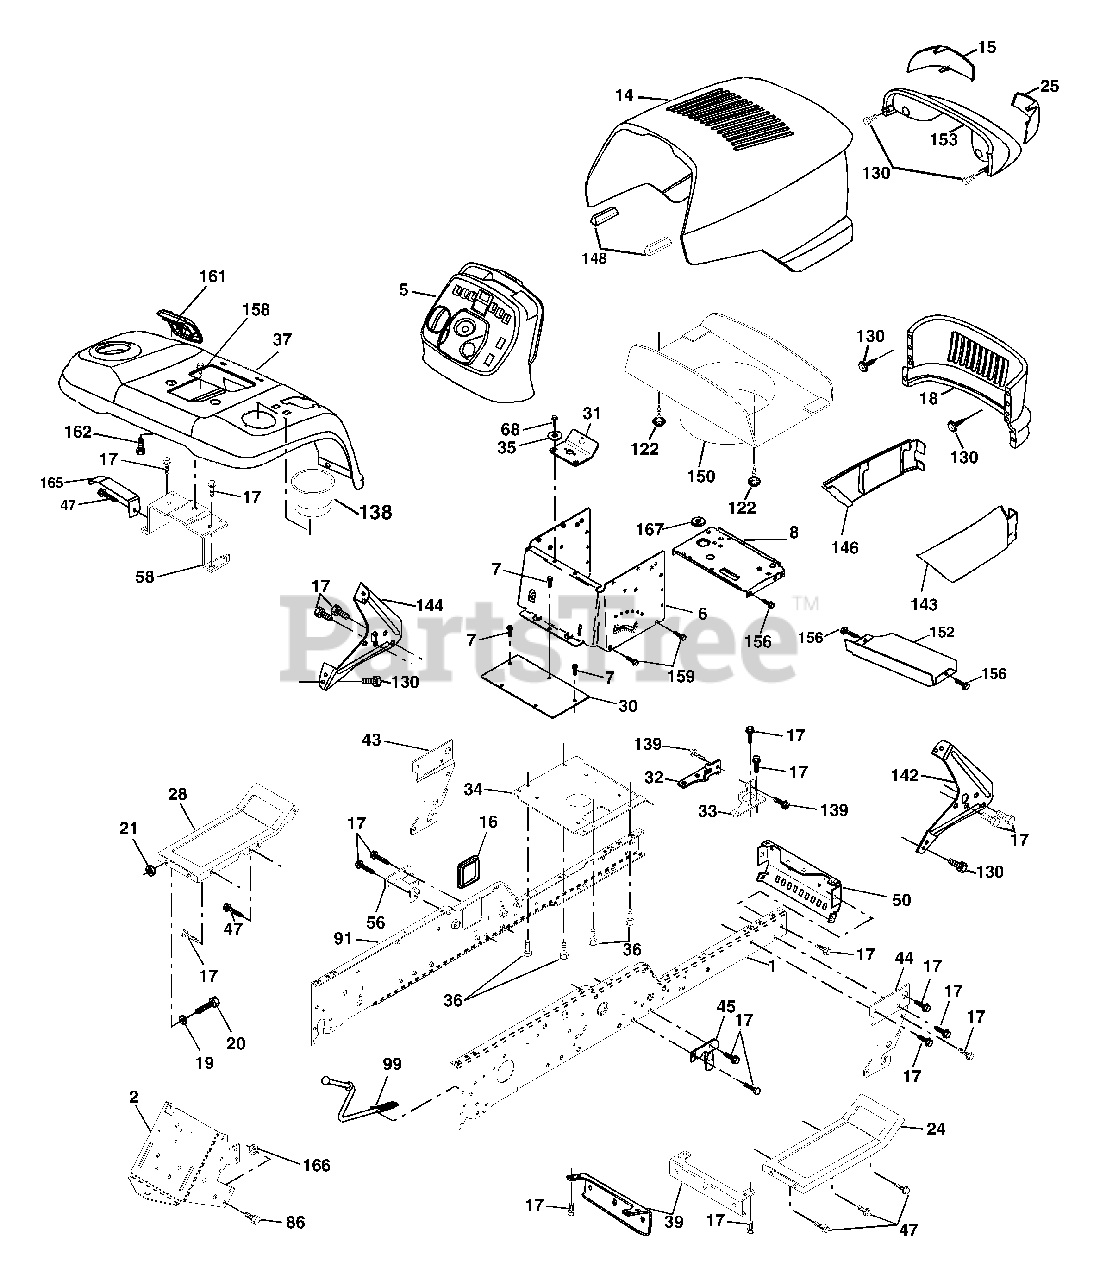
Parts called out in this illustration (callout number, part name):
1	Rail, Frame RH
2	Drawbar, Gt
5	Dash
6	Dash, 1PCS, Lower
7	Screw, Thd Cut 1/4-20 x 1/2
8	Support, Battery
14	Hood Asm., Pnt
15	Lens LH
16	Cover, Access
17	Screw, 3/8-16 x 3/4
19	Washer 13/32 x 13/16 x 12 Ga.
20	Bolt, Fin Hex 3/8-16 x 1
21	Nut, Crownlock 3/8-16
24	Footrest, RH
25	Lens RH
28	Footrest, LH
31	Bracket Supt 1-pc Vgt Steering
32	Bracket, Frame Pivot Lh
33	Bracket, Frame Pivot Rh
34	Plate Asm Engine Chassis
35	Washer 11/32 x 11/16 x 16 Ga.
36	Screw 5/16-18 x 3/4
37	Fender, Pnt.
39	Bracket, Axle Front
43	Bracket, Spnsn Front Lh
44	Bracket, Spnsn Front Rh
45	Bracket Asm., Susp Chassis Rh
47	Screw Thdrol 3/8-16 x 1/2
50	Bracket, Chassis Front
56	Bracket Asm., Susp Chassis Lh
58	Bracket Asm., Fender
68	Screw, 5/16-18 x 1/2
86	Bolt, Fin Hex 7/16-14 unc x 1-1/4
91	Rail, Frame Lh
99	Rod Asm. Bypass
122	Screw Hex WSHD 8-18 x 7/8
130	Screw Hw Hd Hi-Lo #13-16 x 3/4
138	Cupholder
139	Bolt Shoulder 5/16-18
142	Bracket Dash Stealth RH
143	Skirt Grille RH
144	Bracket Dash Stealth LH
146	Skirt Grille LH
148	Extrusion Bumper
150	Duct Heat Hood
152	Shield, Browning
153	Light Box Asm. w/Lens
156	Screw 5/16-18 x 3/4
158	Screw 3/8-16 x 1/2
159	Screw 3/8-16 x 3/4
161	Console Fuel Window
162	Screw Hex 1/4-1/2 unc
165	Bracket Support Tank
166	Nut, Crown Lock 7/16-14 unc
167	Bushing Snap
